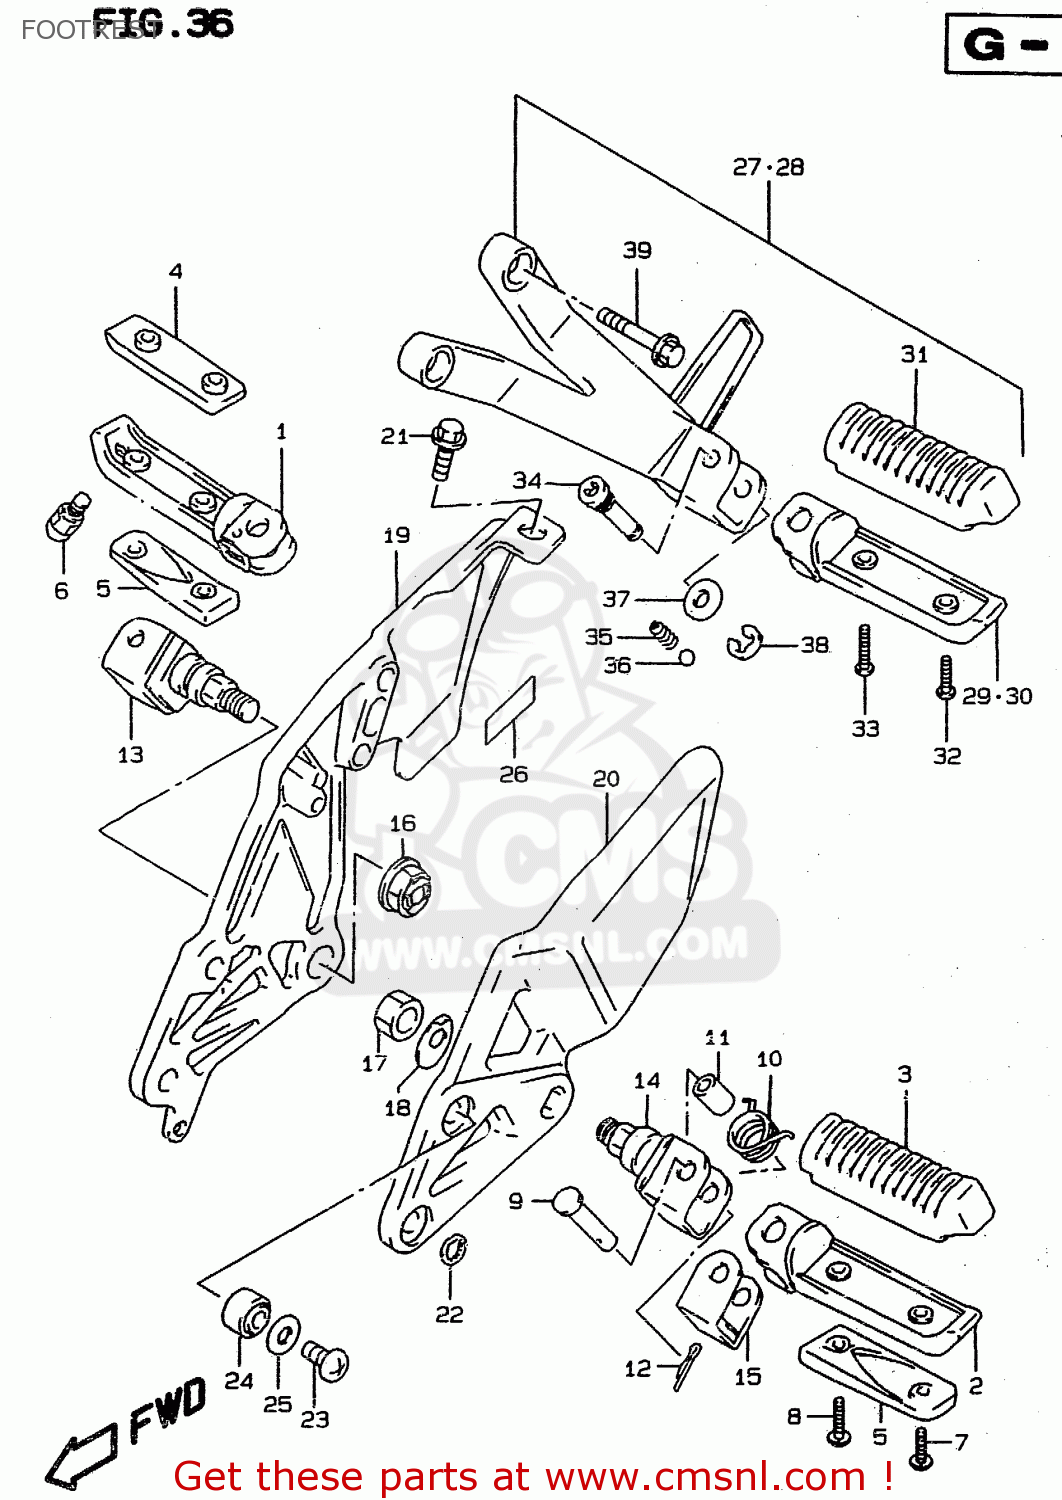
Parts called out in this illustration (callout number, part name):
1	BAR,FR FOOTREST,R
2	BAR,FOOTREST,L
3	RUBBER,FOOTREST
4	BAR,FR FOOTREST NO.2
5	BALANCER,FR FOOTREST LWR
6	SENSOR, RH
7	SCREW
8	SCREW
9	PIN
10	SPRING
11	SPACER(8.1X12X22)
12	PIN 20X15
13	HOLDER,FRONT FOOTREST
14	HOLDER,FR FOOTREST
15	CUSHION,FR FOOTREST
16	NUT 12MM
17	NUT
18	WASHER,FR FOOTREST
19	BRACKET,FOOTREST,R
20	BRACKET,FOOTREST,L
21	BOLT
22	WASHER
23	BOLT(8X25)
24	BUSH
25	WASHER (8.2X24X1.6)
26	PROTECTOR(12X40)
27	FOOTREST ASSY,PILLION,R
28	FOOTREST ASSY,PILLION,L
29	BAR,PILLION FOOTREST,R
30	BAR,PILLION FOOTREST,L
31	RUBBER,FOOTREST
32	SCREW
33	SCREW
34	BOLT,PILLION FOOTREST
35	SPRING
36	BALL
37	WASHER
38	E.RING
39	BOLT(8X20)
